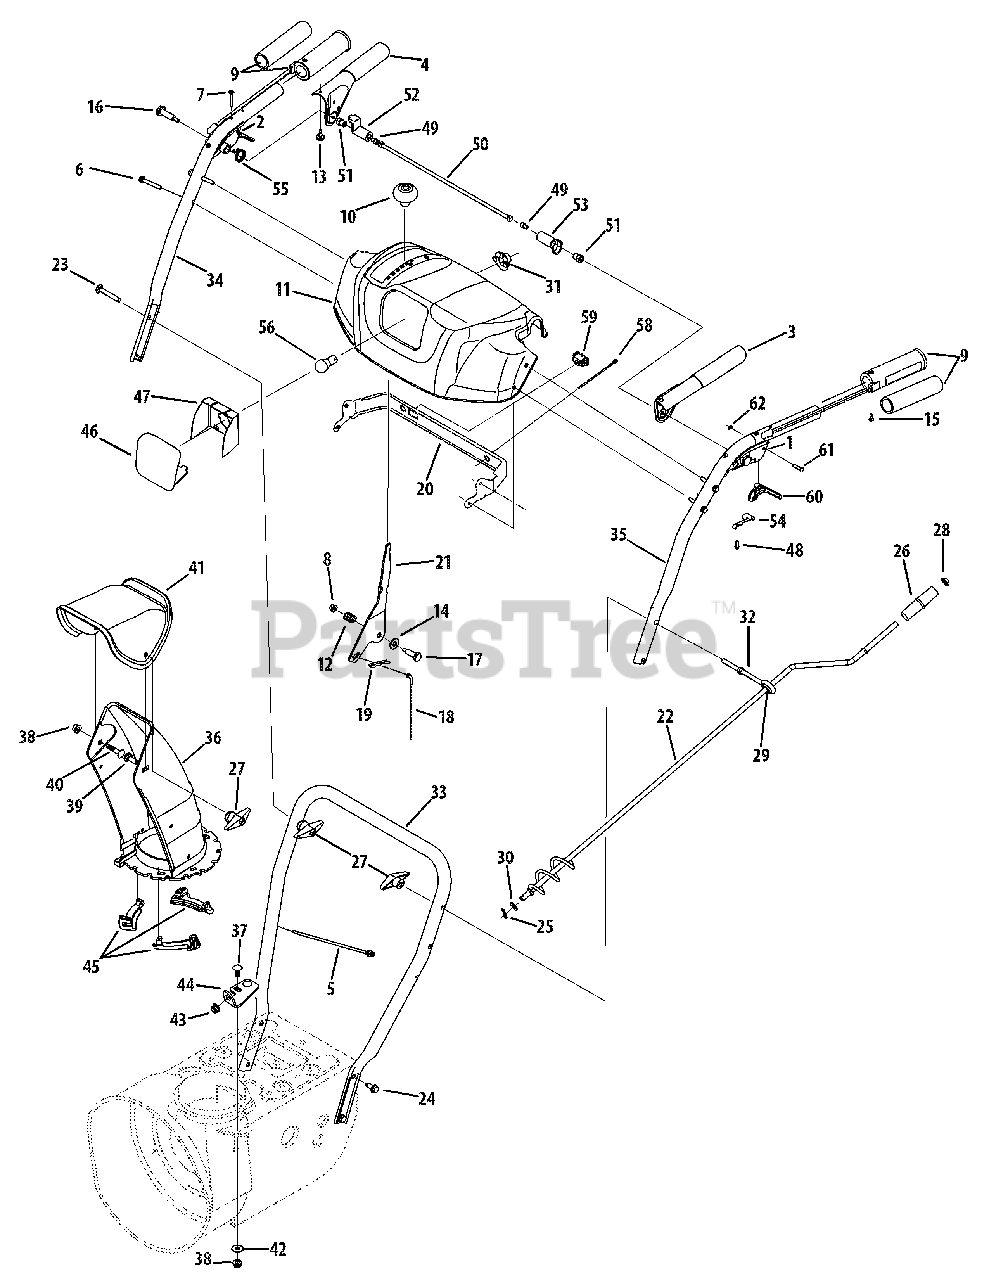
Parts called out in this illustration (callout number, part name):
1	Handle Assembly, Lock LH
2	Handle Assembly, Lock RH
3	Handle Assembly, Engagement LH
4	Handle Assembly, Engagement RH
6	Screw, 1/4-20, 1.625
7	Machine Screw, #10-24, 1.375
8	Flange Lock Nut, 1/4-20, Nylon
11	Handle Panel H-Style
12	Spring, .39 x .60 x .88
13	Rubber Bumper, .62 OD x .22
14	Flat Washer, .385 x .870 x .06
15	AB Screw, 10-16 x .625
16	Shoulder Screw, .43 x 1.34, 1/4-20
17	Shoulder Screw, .374 Dia x 1.05
18	Speed Selector Cable
23	Carriage Screw, 5/16-18, 2.25
24	Hex Screw, 5/16-18, 0.750
25	Cotter Pin, .072 x 1.13
26	Crank Knob, 1.0 Dia x 3.2
28	Push Cap, 3/8 Rod
29	Grommett,, .44 ID x .94 OD x .50
30	Flat Washer, .375 x .738 x .063
31	Light Socket
32	Chute Crank Eye Bolt
37	Carriage Bolt, 5/16-18, 1.0
38	Flange Lock Nut, 5/16-18
39	Carriage Bolt, 5/16-18, 1.0
40	Carriage Bolt, 5/16-18, .750
41	Upper Chute w/ Label
42	Washer, .349 ID x .879 OD x .063
43	Plastic Bushing, .380
45	Chute Flange Keeper
47	Lens Refector Label
48	Screw, #8-16 x 0.50
49	Screw, 1/4-20 x .375
51	Shoulder Nut, 1/4-20
52	Lock Plate
53	Clutch Lock Cam
54	Clutch Lock Spring
55	Torsion Spring
56	Lamp
59	Heated Grip Switch
60	Steering Triggers
